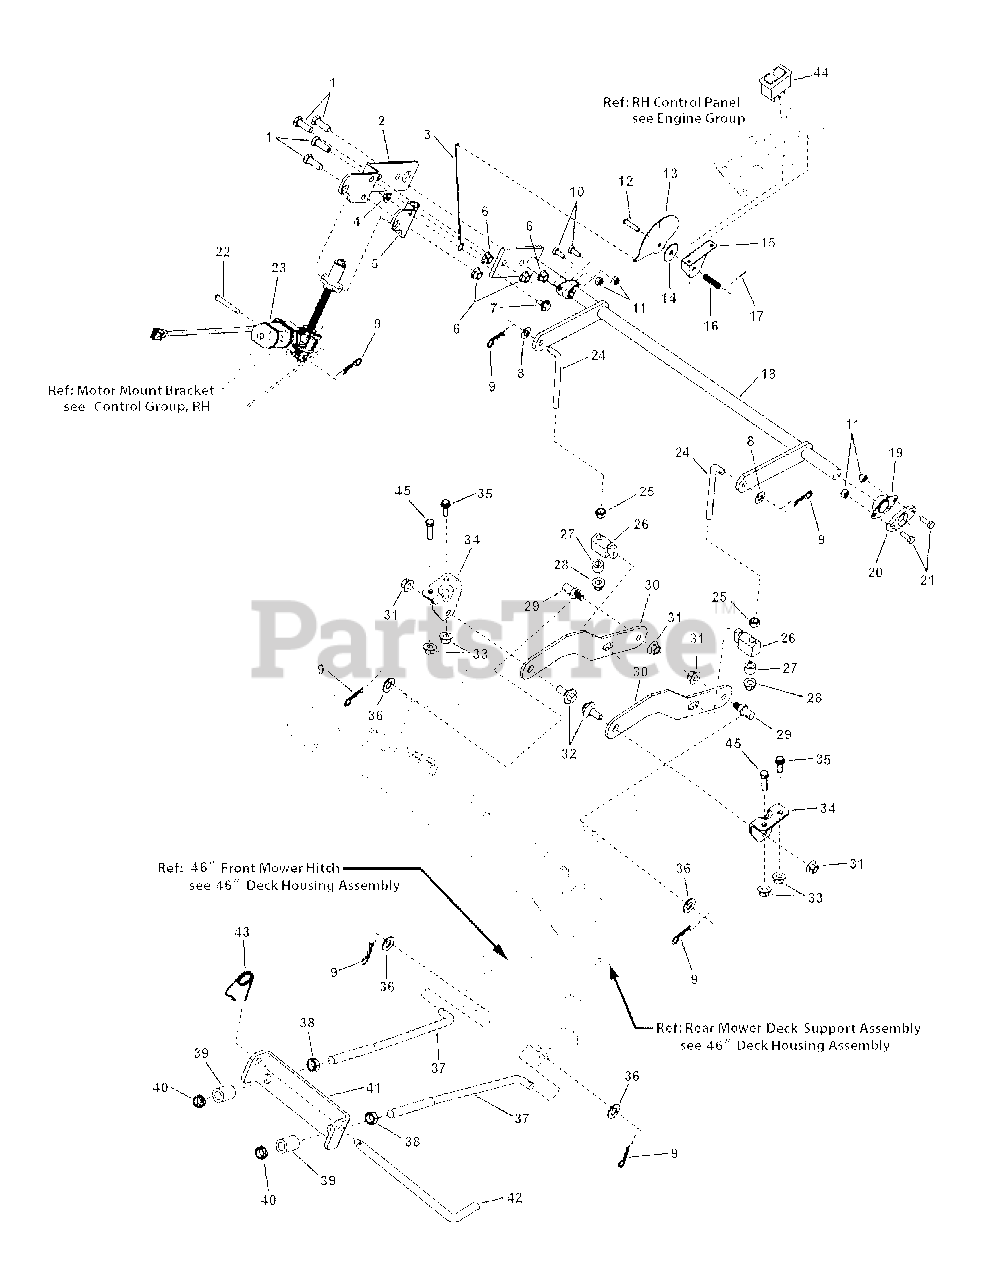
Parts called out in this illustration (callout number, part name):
1	SCREW, 3/8-16 x 1" Hex Head Cap, GR 5, YZ
2	BRACKET, Lift, Deck, Primary
3	ROD, Indicator, Height-Of-Cut
4	NUT, 1/4-20 Hex Flange Lock, GR 5, YZ
5	BRACKET, Lift, Deck, Secondary
6	NUT, 3/8-16 Hex Flange lock, YZ
7	SHOULDER BOLT, 1/4-20 x 3/8"
8	WASHER, 3/8" Flat (SAE)
9	HAIR PIN, 3/32 x 1-1/2" YZ
10	SCREW, 1/4-20 x 5/8" Hex Head Cap, GR 5
11	NUT, 1/4-20 Hex Nyloc, YZ
12	CLEVIS PIN, .25 x 1.09
13	LEVER, Indicator, Height-Of-Cut
14	WASHER, 5/16" Nylon
15	BRACKET, Indicator, Height-Of-Cut
16	SPRING, Compression
17	COTTER PIN, .06 x 1/2" YZ
18	WELDMENT, Deck Lift, 38/42
19	BEARING, Flange, .75 ID PM
20	SPACER, Bearing, .25"
21	SCREW, 1/4-20 x 3/4" Hex Head Cap, GR 5 YZ
22	SHEAR PIN, .248 ID x 1-3/4" Long
23	MOTOR, Actuator, Lift, Deck
24	ROD, Mower Lift (3/8-16 thread) Yellow
25	NUT, 3/8-16 Hex, Black
26	TRUNNION, Powdered Metal, Yellow, Regent
27	SPACER, .385 ID x .6697 OD x .455 Long, PM Yellow
28	NUT, 3/8-16 Hex Flange Esna, Black
29	PIN, 3/8-16 Threaded Shoulder
30	BAR, Rear Lift
31	NUT, 3/8-16 Hex Flange Center Lock, Zinc Plated
32	SHOULDER BOLT, 3/8-16 x .94, BZ
33	NUT, 5/16-18 Flange Lock, YZ
34	BRACKET, Deck Hanger
35	BOLT, 5/16-18 x 5/8" Hex Flange lock, GR 5, YZ
36	WASHER, 1/2" Flat (0.51 ID x 1.00 OD x .10 Thick) Black
37	ROD, Front Bail (1/2-13 thread) 46, 52" MWR
38	NUT, 1/2-13 Hex Jam, Black
39	SPACER, .520 ID x .88 ID x 1.185 YZ
40	NUT, 1/2-13 Jam, Esna Light Thin
41	HANGER, Front Mower
42	ROD, Latch .500 Dia 9" Long 42"
43	CLIP, Hair Pin, .093 Dia Spring Wire Black Zinc
44	SWITCH, Rocker Electric Height-Of-Cut
45	SCREW, 5/16-18 x 1" Hex Head Cap, GR 5, YZ
